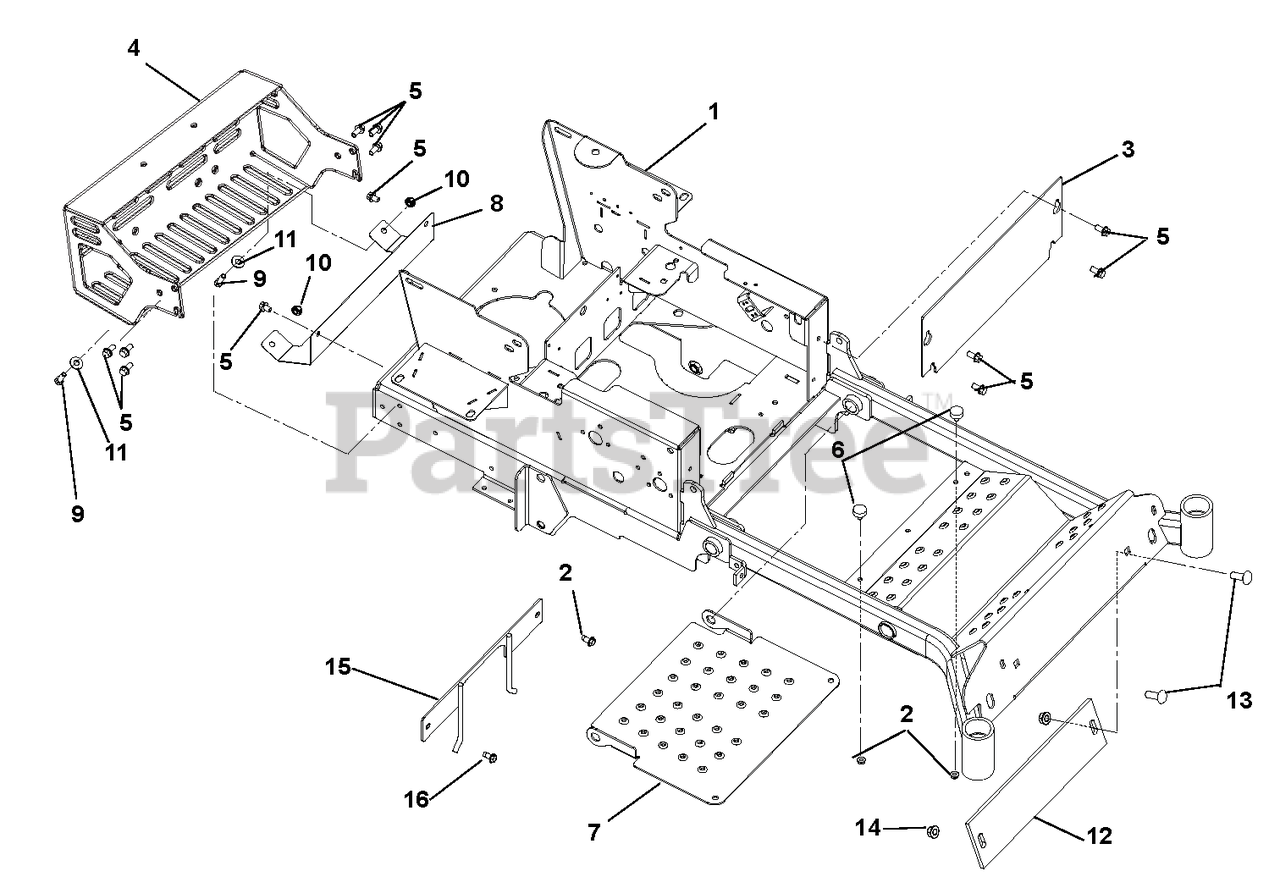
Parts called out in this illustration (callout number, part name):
1	WLDMT, 48" HD FRAME
2	@NUT-SPNLK-FLG .312-18 YWZC
3	PLATE, KICK
4	BUMPER, ARIENS MAX ZOOM
5	@SCR-TAP .38-16X.75 HWH TR YWZ
6	BUMPER, RUBBER
7	PANEL, INSPECTION
8	SHIELD - HEAT - CZ PROD
9	@BLT-HEX .38-16X1.00 GR5 YWZC
10	@NUT-LK-NYL-FLG .38-16 YWZC
11	@WSHR-FL-STL.438X1.00X.083 YWZ
12	COUNTERWEIGHT, CZ FRONT-BLACK
13	BLT-RDHDSQNK .50-13X2.25 G5YZ
14	@NUT-LK-NYL-FLG .50-13 YWZC
15	PTO BELT FINGER WLDMT - BLK
16	@SCR-TAP .38-16X.75 HWH TR YWZ
